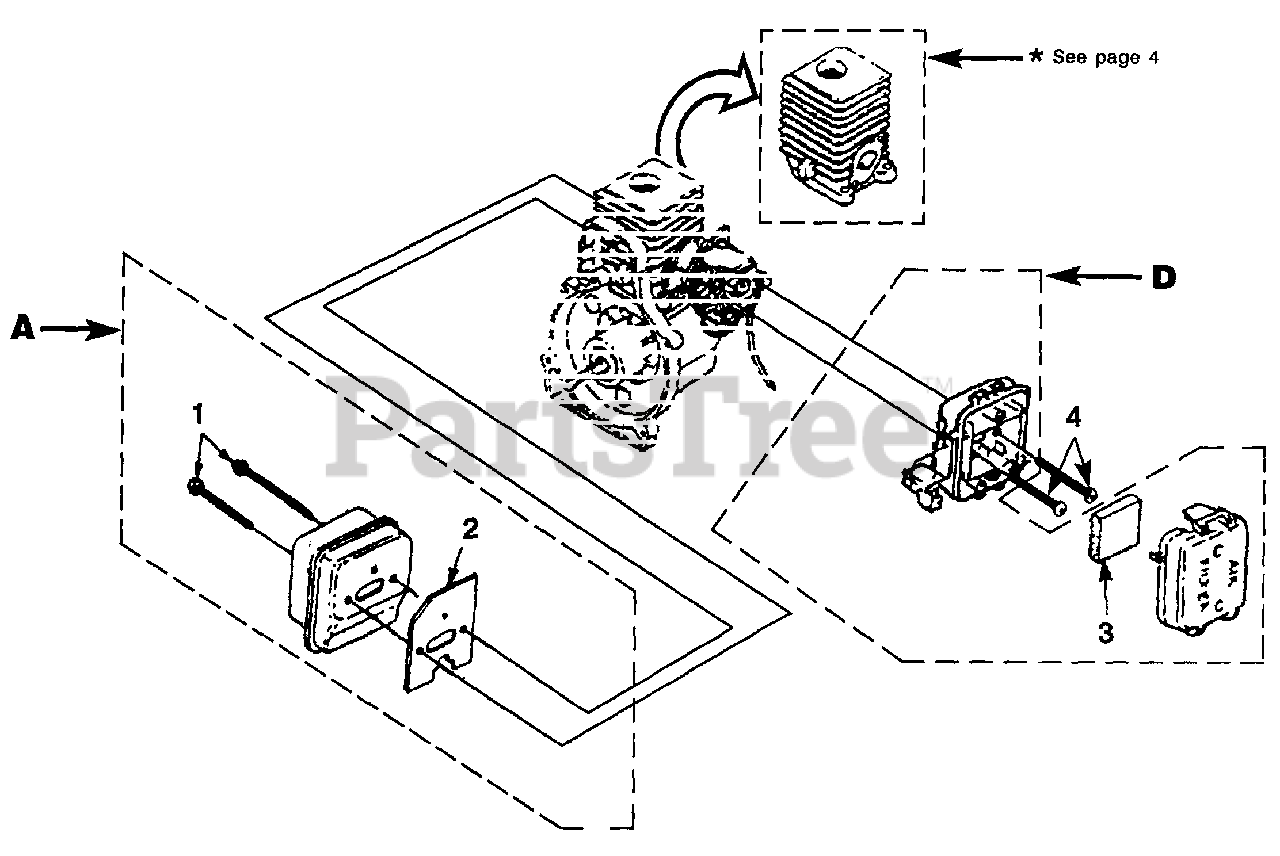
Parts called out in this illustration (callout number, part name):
1	SCREW-Sems Hex (10-24 x 2 1/2")
2	GASKET-Muffler
3	FILTER-AIR
4	SCREW-Sems Hex Hd (10-24 x 2 1/2")
A	MUFFLER COMPLETE
D	AIR FILTER KIT
